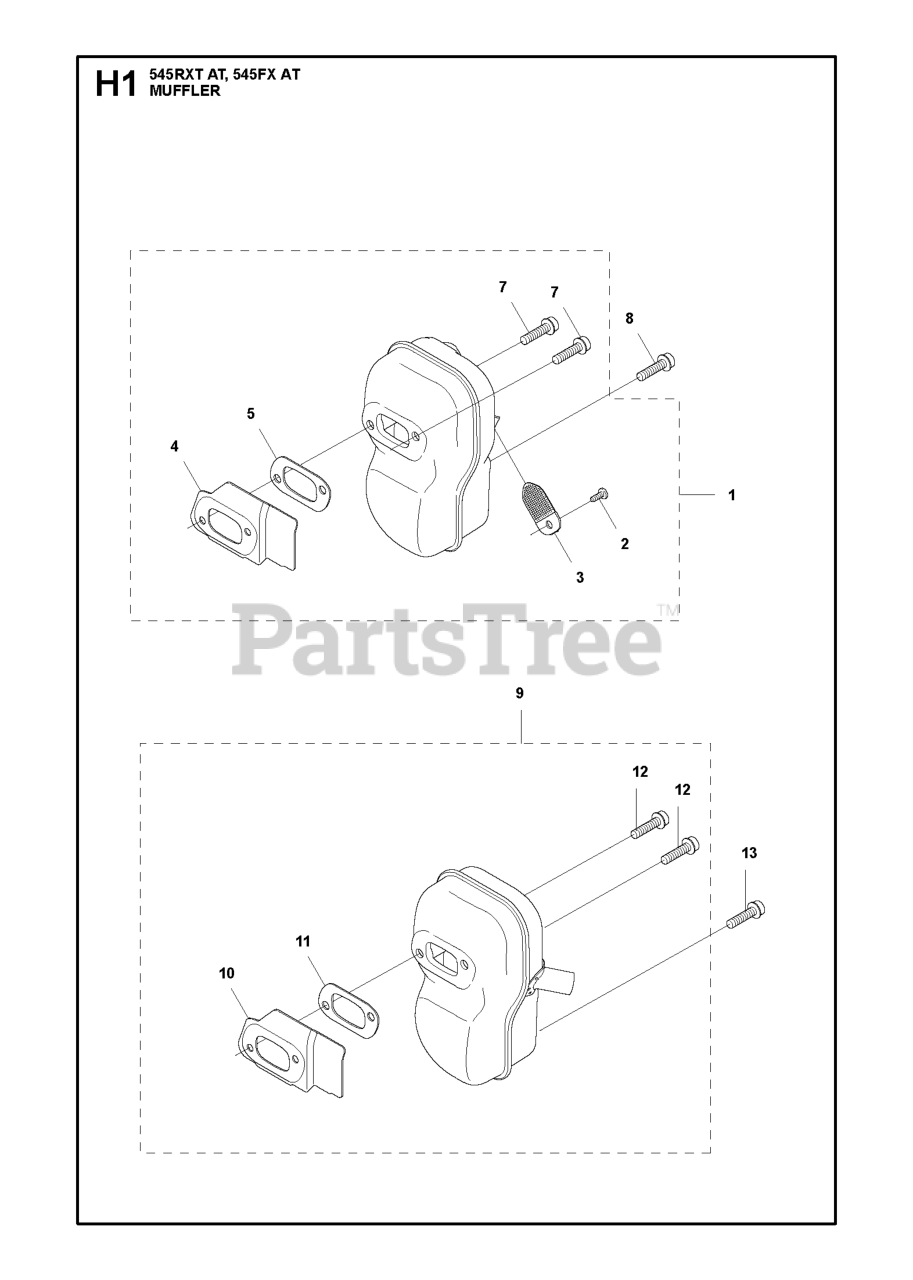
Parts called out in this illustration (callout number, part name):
1	MUFFLER KIT NEW BAFFLE
3	SPARK ARRESTOR SCREEN
4	HEAT DEFLECTOR
9	MUFFLER KIT NEW BAFFLE
10	HEAT DEFLECTOR
